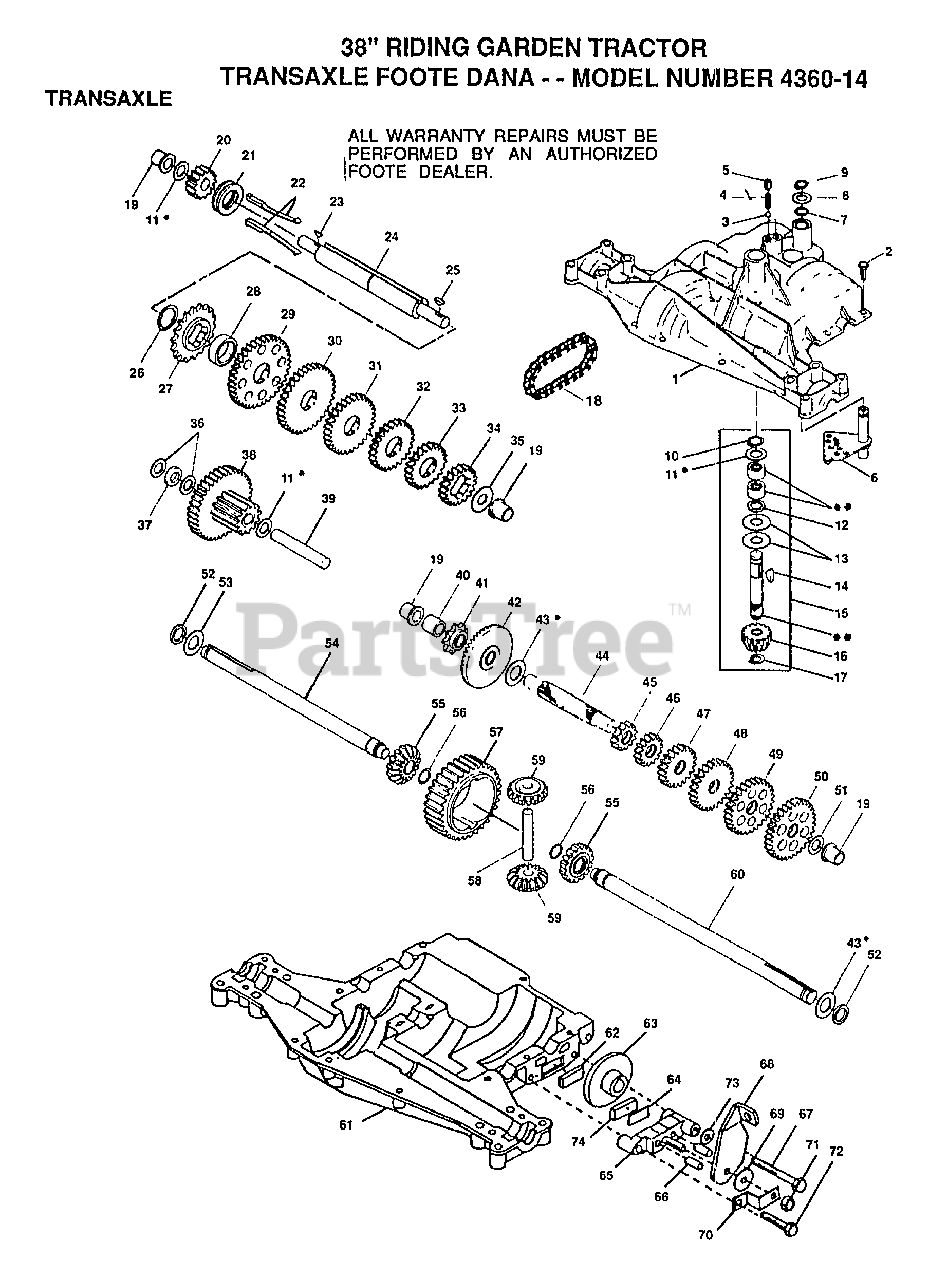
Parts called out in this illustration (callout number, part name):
1	HOUSING UPPER
3	BALL DETENT
4	SPRING, DETENT
5	SCREW, SET
6	ASSY SHIFTER
8	WASHER PLAIN
8A	WASHER PLAIN
8B	WASHER PLAIN
8C	WASHER PLAIN
8D	WASHER PLAIN
8E	WASHER PLAIN
8F	WASHER PLAIN
9	RING RETAINING
10	RING RETAINING
11	WASHER PLAIN
11A	WASHER PLAIN
11B	WASHER, PLAIN .632 X 1.00 X .026
11C	WASHER PLAIN
11D	WASHER PLAIN
11E	WASHER PLAIN
11F	WASHER PLAIN
11G	WASHER PLAIN
11H	WASHER, PLAIN .632 X 1.00 X .060
11I	WASHER PLAIN
13	WASHER, PLAIN .632 X 1.38 X .046
14	KEY WOODRUFF #9
15	ASSY KIT INPUT SHAFT
16	PINION, BEVEL, 14 TEETH
17	RING, RETAINING
18	CHAIN, 24 PITCHES
19	BEARING, FLANGE
20	GEAR SPUR, 14 TEETH
21	COLLAR CLUTCH
22	KEY CLUTCH
23	KEY WOODRUFF #3
24	SHAFT INTERMEDIATE
25	KEY, WOODRUFF, #61
26	RING, RETAINING
27	SPROCKET, 18 TEETH
29	GEAR, SPUR, 37 TEETH
30	GEAR, SPUR, 35 TEETH
31	GEAR, SPUR, 30 TEETH
32	GEAR, SPUR, 25 TEETH
33	GEAR, SPUR, 22 TEETH
35	WASHER, PLAIN .640 X 1.37 X .061
36	WASHER, PLAIN .632 X 1.00 X .026
37	SPACER .630 X 1.00 X .169
38	ASSY GEAR COMB 12&35 TEETH
39	SHAFT IDLER
40	SPACER .635 X .875 X .755
41	SPROCKET, 9 TEETH
42	GEAR, BEVEL, 42 TEETH
43	WASHER PLAIN
43A	WASHER PLAIN
43B	WASHER PLAIN
43C	WASHER PLAIN
43D	WASHER PLAIN
43E	WASHER PLAIN
43F	WASHER, PLAIN .758 X 1.25 X .031
43G	WASHER PLAIN
43H	WASHER PLAIN
43I	WASHER PLAIN
43J	WASHER PLAIN
43K	WASHER PLAIN
43L	WASHER PLAIN
44	SHAFT, DRIVE
45	GEAR, SPUR, 12 TEETH
46	GEAR SPUR, 15 TEETH
47	GEAR, SPUR, 20 TEETH
48	GEAR, SPUR, 25 TEETH
49	GEAR, SPUR, 28 TEETH
50	GEAR, SPUR, 31 TEETH
51	WASHER, PLAIN .632 X 1.00 X .060
53	WASHER PLAIN
54	AXLE LEFT HAND
55	GEAR MITER 15 TEETH
56	RING, RETAINING
57	GEAR, SPUR, 32 TEETH
58	SHAFT, CROSS
59	GEAR, MITER, 15 TEETH
60	AXLE, R.H.
61	HOUSING LOWER
62	PUCK, FRICTION
63	DISC, BRAKE
65	JAW, BRAKE
66	PIN, DOWEL
67	SCREW TAPPING
68	LEVER, ACTUATING
69	WASHER, PLAIN .321 X 1.00 X .055
70	BRACKET, ANTI-ROTATION
71	LOCKNUT 5/16-24
72	SCREW TAPPING
73	WASHER PLAIN
74	PUCK, FRICTION
